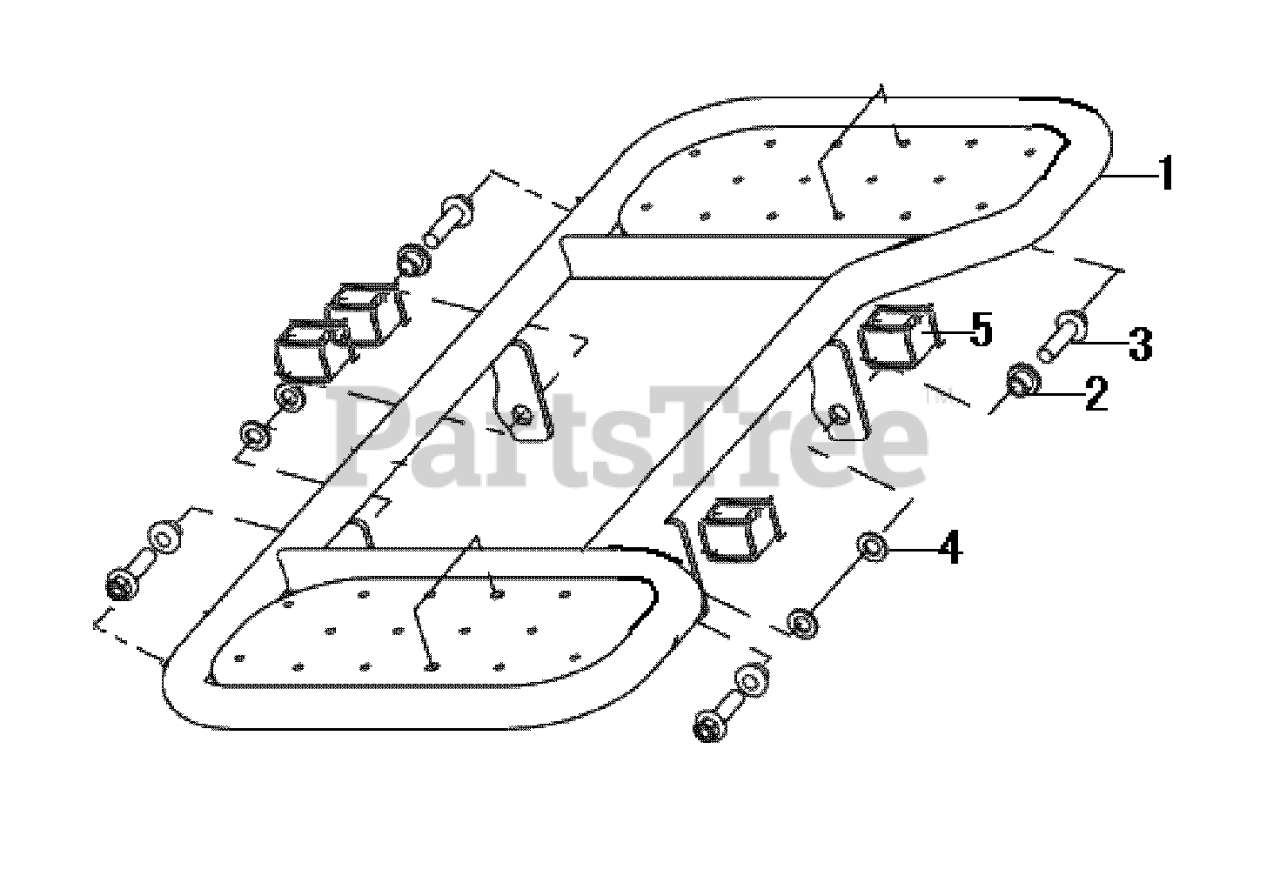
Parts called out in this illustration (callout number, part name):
1	FOOTREST ASSY.
2	RUBBER BUSHING
5	RUBBER PAD
